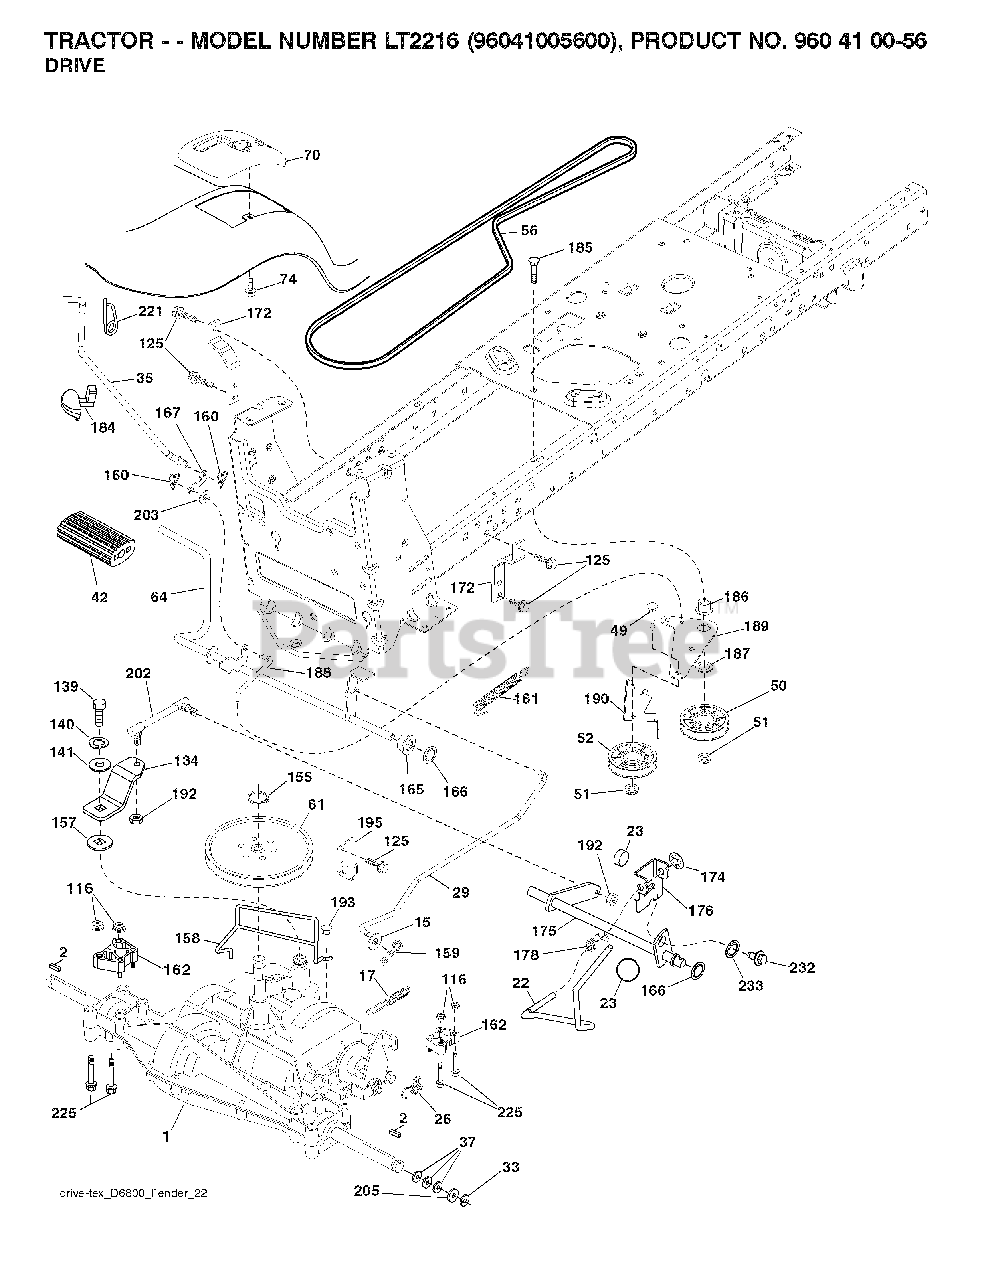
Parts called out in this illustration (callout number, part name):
2	SQUARE KEY
17	SPRING.BRAKE.PEERLESS.TEX
22	ROD.SHIFT.FENDER.TLT.2006
23	KNOB.DUCKHEAD.1/2
26	SPRING.BRAKE.RTN.GR.DR
29	ROD.BRAKE.PEERLESS
33	E-RING LT
35	ROD.BRAKE.PARKING.LT.T
42	PEDAL COVER T
49	BOLT
50	IDLER.FLAT.910.OFFSET
51	NUT LOCK FLG 3/8-16 UNC
52	IDLER.V-GROOVE.910.OFFSET
61	PULLEY TRANS
64	SHAFT.ASM.PEDAL.BRAKE.
70	CONSOLE.SHIFT.
74	SCREW.HI-LO.CONSOLE
116	NUT LOCK HEX FLANGE 5/16-18
125	SCREW
134	ARM.SHIFT.
139	BOLT 1/4-28X3/4
140	LOCKWASHER
141	WASHER LT
155	RETAINING RING LT
157	WASH-SHFT PLT LT
158	KEEPER.PMS.18/20.D4365
159	COTTER PIN
160	RETAINER CLIP
161	SPRING.RETURN.CLUTCH.2006
162	SPACER.TRANSAXLE.18&22
165	BUSHING.SHAFT.BRAKE.HAND
166	NUT.PUSH.625.2006
167	LATCH.BRAKE.SPRING
172	STRAP.TRQ.LH.GEAR.DRIV
174	NUT.PUSH.500.2006
175	SHAFT.ASM.SHIFT.
176	ARM.CLEVIS.ROD.SHIFT
178	SPRING.SHIFT.GT2006
184	HANDLE.PAKRING.BRAKE.
186	SPACER.RETAINER
187	WASHER 12/32X2X10GA
188	LINK.CLUTCH.GROUND.DRIVE
189	BELLCRANK.GROUND.DRIVE.TEX.
190	KEEPER.BELLCRANK.DRIVE
192	NUT LOCK CENTER 1/4 -28 FNTHD
193	SCREW 5/16"
195	BRKT.ROD.BRAKE.PEERLES
202	LINK.TRANSAXLE.
203	WASHER
221	RETAINER.SPRING.CLIP.H
225	BOLT.HEX.FLNG.5/16-18X3.75
232	BOLT FIN HEX 7/16-14 X 1
233	WASHER SERRATED
